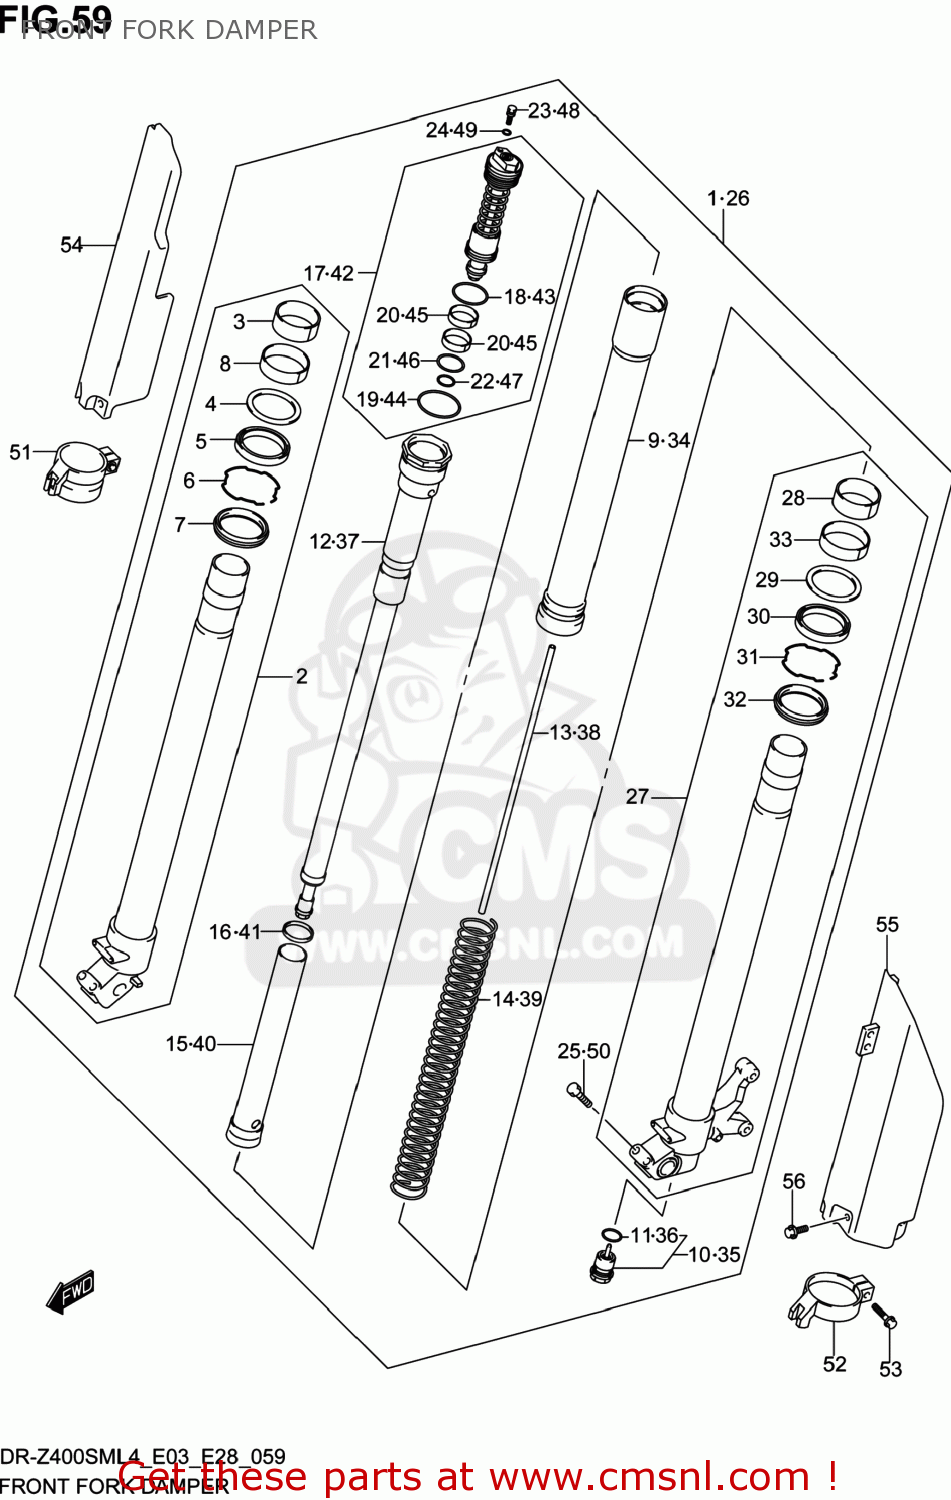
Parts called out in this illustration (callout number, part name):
1	DAMPER ASSY,FR FORK,R
2	TUBE,INNER,R
3	BUSH,GUIDE
4	SPACER,SEAL
5	SEAL,OIL
6	RING,OIL SEAL STOPPER
7	SEAL,DUST
8	BUSH,SLIDE
9	TUBE,OUTER
10	BOLT,CTR
11	O RING
12	DAMPER
13	ROD,PUSH
14	SPRING,FR
15	COLLAR,SPRING
16	SPRING SEAT
17	BOLT,FORK
18	O RING
19	O RING
20	BUSH,FORK BOLT SLIDE
21	O RING
22	O RING
23	BOLT,PLUG
24	O RING,PLUG
25	BOLT
26	DAMPER ASSY,FR FORK,L
27	TUBE,INNER,L
28	BUSH,GUIDE
29	SPACER,SEAL
30	SEAL,OIL
31	RING,OIL SEAL STOPPER
32	SEAL,DUST
33	BUSH,SLIDE
34	TUBE,OUTER
35	BOLT,CTR
36	O RING
37	DAMPER
38	ROD,PUSH
39	SPRING,FR
40	COLLAR,SPRING
41	SPRING SEAT
42	BOLT,FORK
43	O RING
44	O RING
45	BUSH,FORK BOLT SLIDE
46	O RING
47	O RING
48	BOLT,PLUG
49	O RING,PLUG
50	BOLT
51	GUIDE,PROTECTOR,R
52	GUIDE,PROTECTOR,L
53	BOLT
54	PROTECTOR,FR FORK,R
55	PROTECTOR,FR FORK,L
56	BOLT(6X10)
